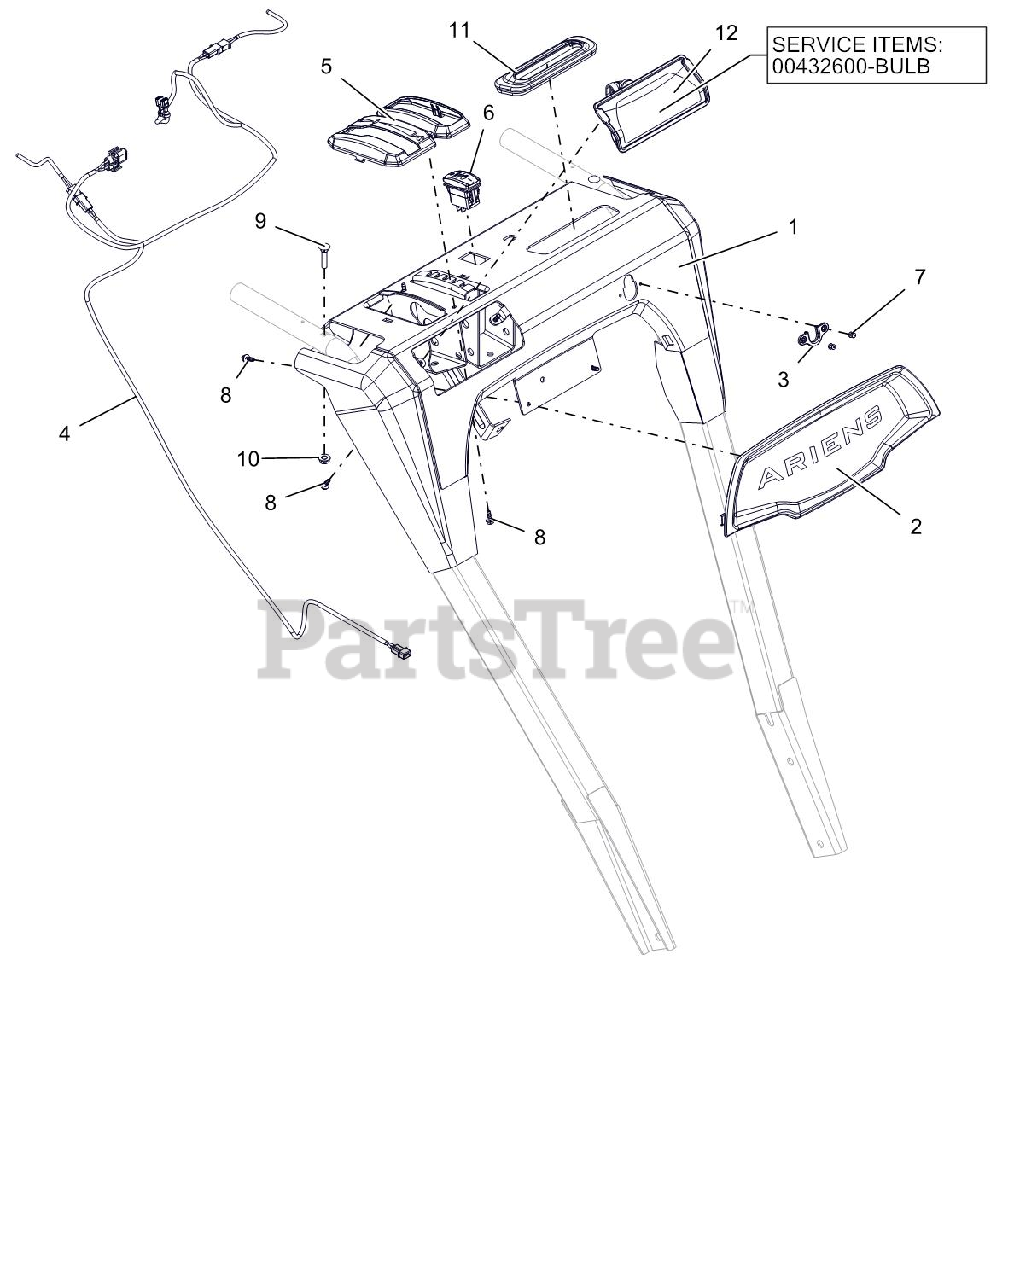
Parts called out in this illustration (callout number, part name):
1	PANEL, DASH-HYDRO W/DECAL
2	BEZEL, DASH - ARIENS LG DASH
3	GROMMET, CABLE, QUICK TURN 2
4	HARNESS, LIGHT & WARMER
5	BEZEL, SHIFT - HYDRO SNOW
6	SWITCH,ROCKER SPST-ON/OFF
7	RVT-POP #43 .125X.313 STL ZINC
8	SCR-TAP #10X.50 BOSS INDHXHD
9	BLT-RDHDXLSQNK.25-20X1.25 G5ZC
10	@NUT-LK-CTR-FLG .25-20 YWZC
11	GROMMET, BOOT, QUICK TURN
12	BULB, LIGHT-HALOGEN 20W
12	HEADLIGHT ASY, HALO 20W 2SHOT
